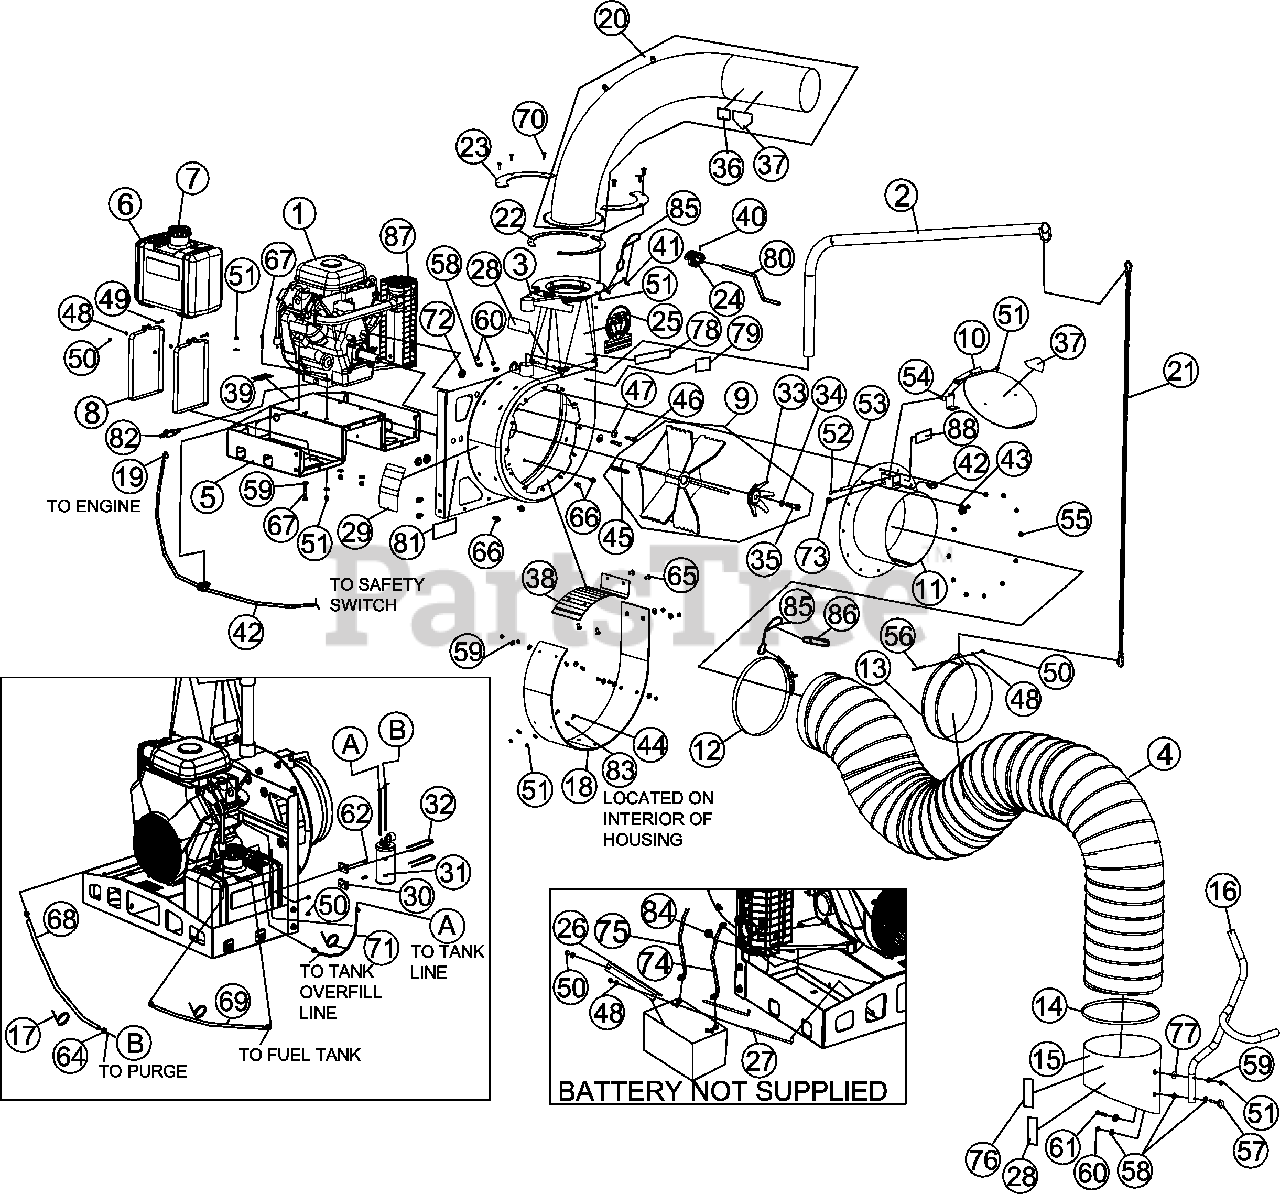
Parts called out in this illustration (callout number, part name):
1	ENGINE BRIGGS VANGUARD 35 HP
2	BOOM HOSE WA
3	INTAKE HOUSING WA W/LABELS
4	HOSE 14" INTAKE X 10'
5	ENGING BASE WA W/LABELS
6	FUEL TANK ASSY
7	CAP TANK FUEL SIX GAL
8	CLAMP TANK FUEL
9	IMPELLER ASSY
10	FLAPPER INTAKE 14" W/LABELS
11	INTAKE HOUSING WA 14" LOADER
12	CLAMP T-BOLT OVERCENTER 14" HOSE
13	BAND HOSE BOOM 14.50" FORMED
14	CLAMP HOSE 14" RAW
15	NOZZLE INTAKE 14" FORMED
16	HANDLE NOZZLE GRIP ASSY
18	LINER REPLACEABLE LOADER
19	TERMINAL 18-14 BLUE T-TAP
20	ELBOW 8" WA DL W/LABELS
21	CHAIN HONG HOSE DL 18/25
22	PLATE CLAMP SPLIT DL
23	PLATE CLAMP HALF DL
24	GEAR WORM WA
25	LABEL PRODUCT DECAL DL
26	BATTER BRACKET
27	ROD BATTERY HOLD DOWN
28	LABEL WARNING ENGINE OVERHEAT
29	LABEL INSTRUCTION WARNING
30	BRACKET CARBON CANISTER
31	CANISTER CARBON 400cc
32	CABLE TIE
33	PIRANHA BLADE WA DL3500V
34	WASHER LOCK 5/8 S/T MED
35	SCREWCAP 5/8"-18 3" ZP GR 8
36	LABEL WARNING OPEI
37	LABEL DANGER
38	CUT OFF REPLACEABLE DL
39	LABEL WARNING SECURE
40	PIN ROLL 3/16" X 0.875" ZP
41	LYNCH PIN 3/16" X 1 9/16"
42	SWITCH AND WIRE HARNESS DL
43	CLAMP ROUTING FUEL LINE
44	SCREW BUTTON HEAD 5/16" X 0.75
45	KEY 3/8" SQUARE X 4.5"
46	SCREWCAP 7/16"-14 X 2 1/4" GR. 5 W/PATCH
47	WASHER LOCK 7/16" TWISTED TOOTH
48	WASHER 1/4" SAE
49	BOLT CARRIAGE 1/4"-20 X 1 3/4" ZP
50	NUT LOCK 1/4"-20 HEX ZP
51	NUT LOCK 5/16"-18 HEX ZP
52	BOLT CARRIAGE 5/16"-18 X 3 1/2" ZP
53	SPACER 3/8" X 2 1/2"
54	LEVER HOSE SWITCH
55	NUT LOCK 3/8"-16 SER HEX WSHR FLNG
56	SCREWCAP 1/4"-20 X 3"
57	BOLT EYE G-2 3/8" X 2"
58	WASHER 3/8" FLAT
59	WASHER 5/16" FLAT
60	NUT LOCK 3/8"-16 HEX
61	SCREWCAP 5/16"-18 X 2" HCS ZP
62	SCREWCAP 1/4"-20 X 3/4" HCS ZP
63	BARB ADAPTER 3/16 TO 1/4"
64	CLAMP HOSE FUEL LINE
65	BOLT CARRIAGE 3/8"-16 X 1" ZP
66	SER HEX WSHR FLNG SCREW 0.375"-16 X 3/4"
67	SCREWCAP 5/16"-18 X 2 1/2" HCS ZP
68	FUEL LINE 1/4" ID X 24"
69	FUEL LINE 1/4" ID X 10.5"
70	BOLT CARRIAGE 5/16"-18 X 1"
71	FUEL LINE 1/4" ID X 17.0"
72	GROMMET 1" HOLE
73	STRAIN RELIEF HEYCO 1244
74	BATTERY CABLE RED 36"
75	CABLE BATTERY BLACK 20"
76	LABEL WARNING NOZZLE
77	WASHER FLAT FENDER 5/16"
78	LABEL DL PIRANHA
79	LABEL MADE IN USA
80	SHAFT WORM GEAR
81	LABEL EPA COMPLIANCE
82	PLUG OIL DRAIN DL35
83	WASHER 5/16 SAE
84	GROMMET 1.0" ID
85	LANYARD PLASTIC 10"
86	PIN SAFETY
87	MUFFLER ASSY DL35
88	LABEL WARNING LINER DL
